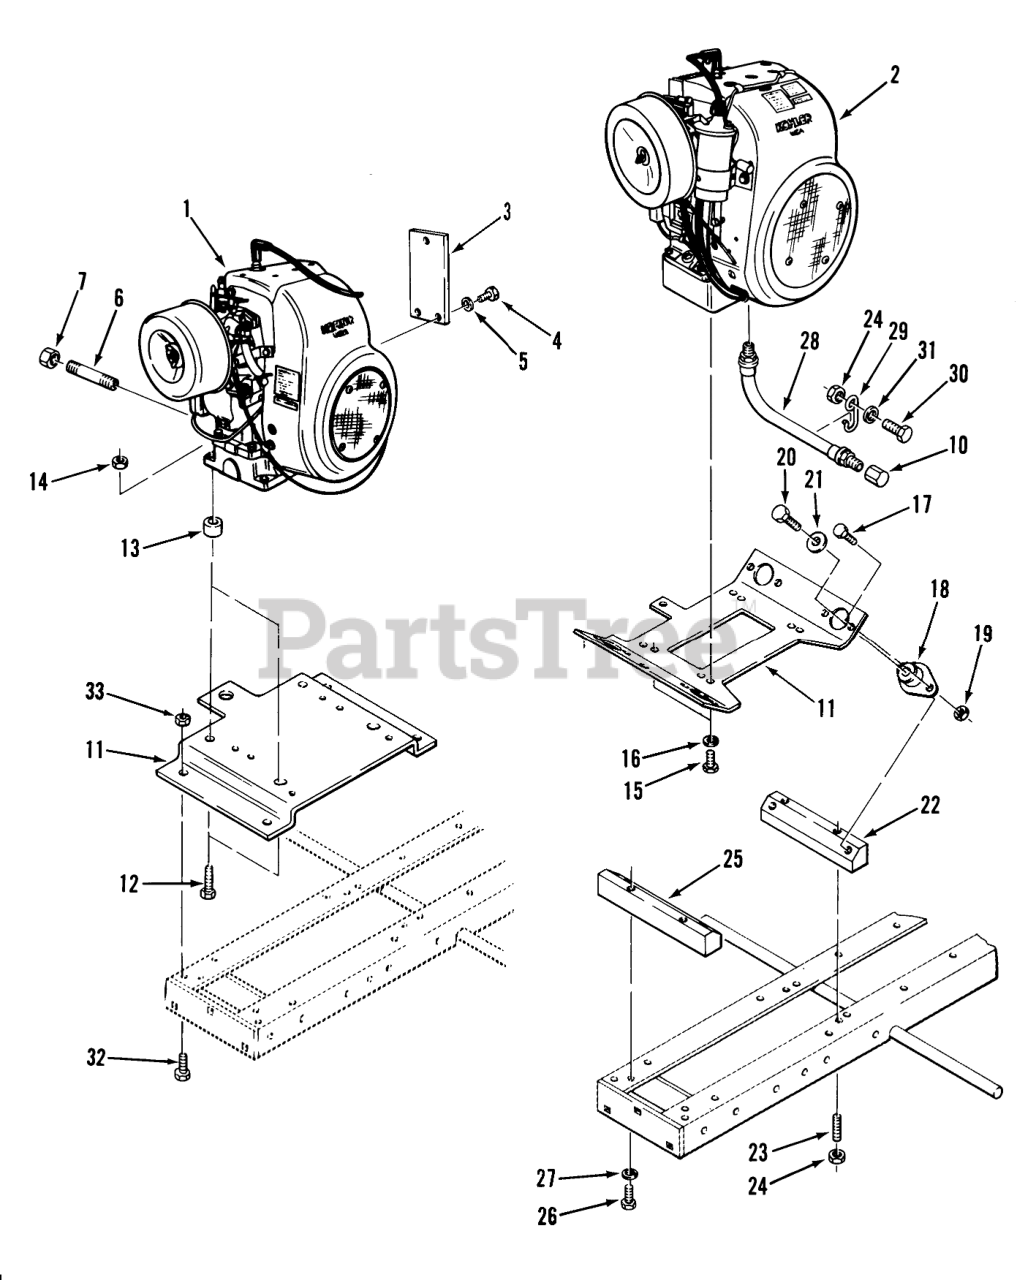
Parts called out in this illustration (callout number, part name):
1	Engine-8HP Kohler K-1815 Spec PS-30743D
1	Engine-8HP Kohler K-181S Spec PS-30803 (Later Production)
2	Engine-14 HP Kohler K-321AS Spec 60373
2	Engine-10 HP Kohler K-241AS Spec 46812
2	Engine-12 HP Kohler K-301AS Spec 47742
3	PLATE COIL & SOL MTG
4	BOLT
5	LOCKWASHER
6	Nipple 1/2"
7	CAP-PIPE 1/2 IN
10	CAP 1/4 PIPE
11	Engine Cradle
11	BASE ENGINE R
12	Bolt
13	SPACER
14	Nut
15	Bolt
16	LOCKWASHER
17	H H C S
18	MOUNT-ISOLATION
19	Nut
20	Bolt
21	Washer
22	MOUNT-BLOCK-REAR
23	SET SRW 3/8X16-1 3/4
24	Nut
25	Engine Mounting Block-Front
26	BOLT
27	LOCKWASHER
28	ASM-HOSE
29	RETAINER-HOSE
30	Bolt
31	Washer
32	BOLT
33	NUT
